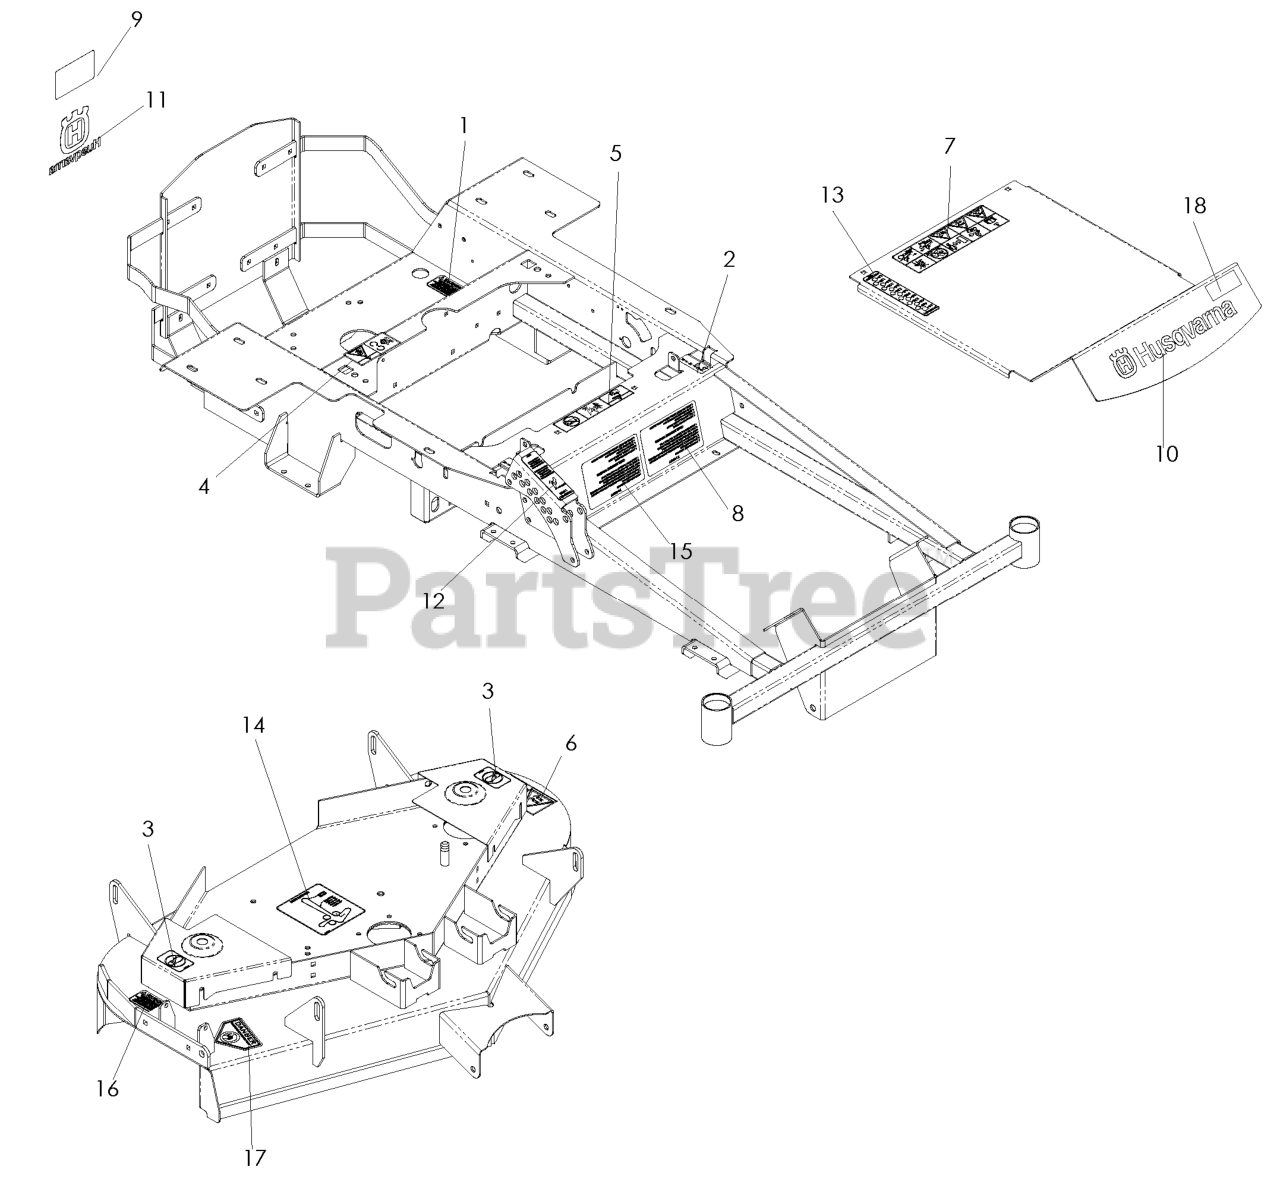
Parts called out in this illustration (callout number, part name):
1	DECAL, PROP. 65
2	DECAL, MOTION CONTROL
3	DECAL, NO STEP
4	DECAL, BELT DRIVE
5	EURO DECAL-BATTERY WARNIN6
6	DECAL, EURO SEVERING
7	DECAL, WARNING
8	DECAL, START
9	DECAL, DO NOT TOW
10	DECAL, HUSQ 12" BLUE
11	DECAL, CROWN H 5-1/4 SILVER
12	DECAL, TRANS RELEASE
13	DECAL, HEIGHT ADJUST
14	DECAL, BELT ROUTING
15	DECAL, WARNING
16	DECAL, CAUTION
17	DECAL, CPSC
18	DECAL, EZ4220
